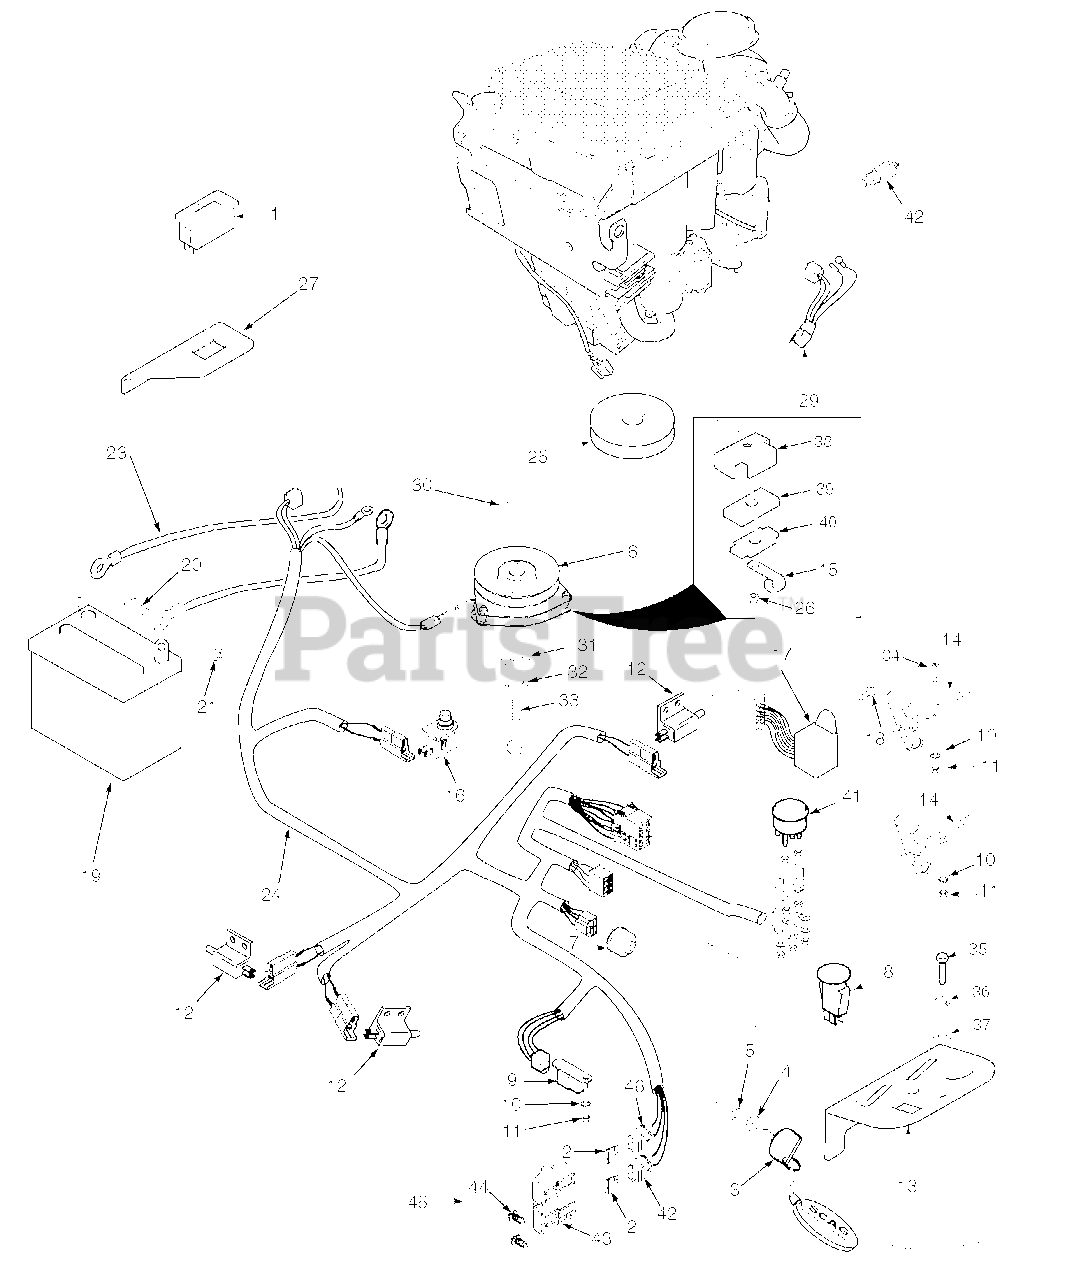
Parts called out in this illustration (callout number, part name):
1	Hourmeter
2	Fuse, 20 amp
3	Key, Ignition
4	Nut, Hex 5/8-32
5	Lockwasher, 5/8" Internal
6	Electric PTO Clutch GT3.5
7	Switch, Ignition
8	Switch, PTO
9	Relay
10	Lockwasher, #10 External Tooth
11	Nut, Hex #10-32
12	Switch, N/O
13	Panel, Instrument
14	Choke & Throttle Control
16	Switch, Seat
17	Module, Interlock
18	Screw, #10-32 x .5" Phillips Head
19	Battery
20	Bolt, Hex Hd. 1/4-20 x .5"
21	Nut, Hex 1/4-20
22	Cable, Battery Black
23	Cable, Battery Red
24	Wiring Harness, Main
25	Pulley, 5.45" OD x 1.125" Bore
26	Nut, Elastic Stop 5/16-18 Key
27	Mounting Bracket, Hour Meter
28	Screw, #10-32 x 1.5" Phillips Head
29	Adaptor, Wiring Harness
30	Key, 1/4 x 1/4 x 3-1/4"
31	Flatwasher, 7/16 (.469 x 1-3/4" x 1/4")
32	Lockwasher, 7/16"
33	Bolt, Hex Hd. 7/16-20 x 2-1/4" UNF
34	Screw, #10-32 x 3/4"
35	Bolt, Hex Hd. 5/16-18 x 3/4"
36	Lockwasher, 5/16"
37	Flatwasher, 5/16 (.375 x .875 x .083")
38	Backing Plate
39	Rubber Pad, Clutch Stop
40	Plate, Backing
41	Water Temp. Gauge
42	Sender Unit, Water Temp
43	Cover, Sealed Double
44	Clip, Wire
45	Double Fuse Assembly, Sealed
46	Fuse Holder
